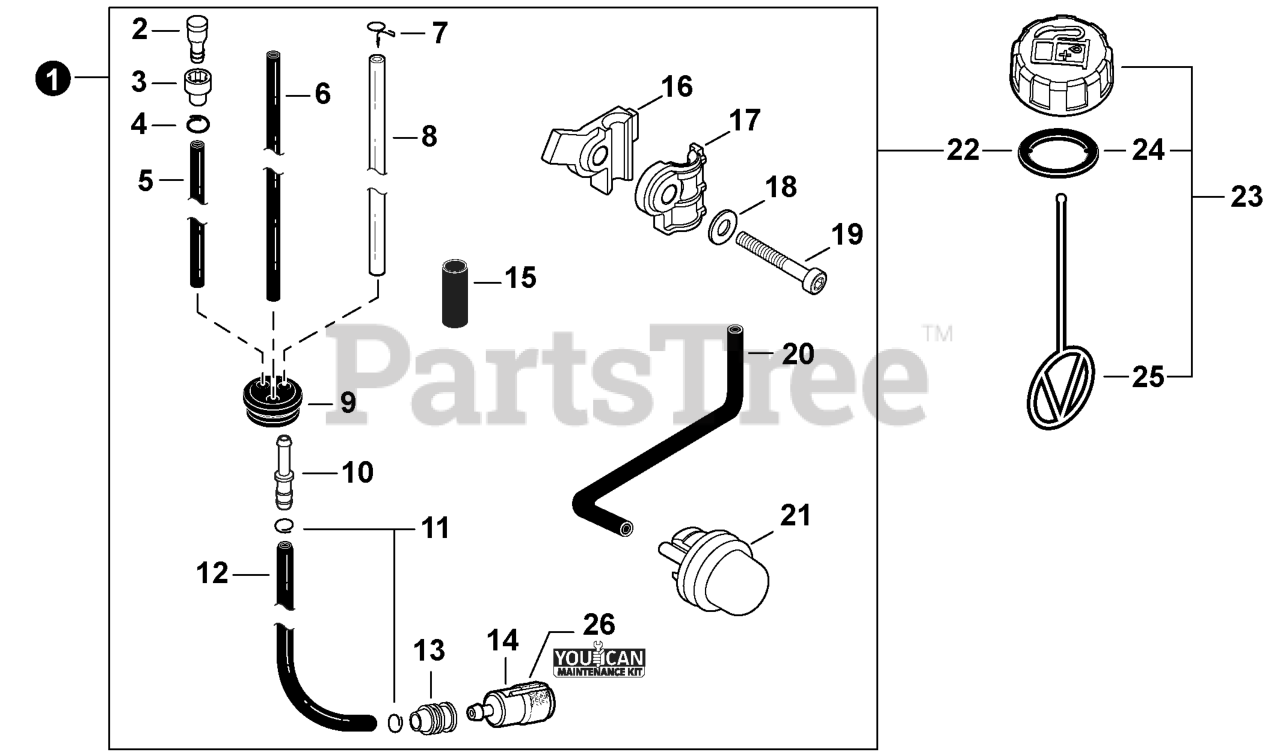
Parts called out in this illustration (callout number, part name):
1	FUEL SYSTEM KIT
2	VENT ASSY
3	HOLDER, VENT
4	CLIP 6.5 MM
5	PIPE, FUEL 3x6x130 BLACK
6	PIPE, FUEL 2.4x5x200 BLACK
7	CLIP, SPRING 5.2
8	PIPE, FUEL 3.5x6x210 CLEAR
9	GROMMET, FUEL
10	CONNECTOR, PIPE 5x3.5
12	PIPE, FUEL 3x5x105L BLACK
14	FILTER, FUEL
15	TUBE, FUEL LINE 16x18xL40
16	CLAMP, LOWER
17	CLAMP, UPPER
18	WASHER, FLAT 5.5x10x0.8
19	BOLT, TORX 5x25
20	PIPE, PURGE 2.4x5x140 BLACK
21	BULB, PURGE
22	GASKET, FUEL CAP
23	CAP ASSY, FUEL
24	GASKET, FUEL CAP
25	CONNECTOR, CAP L= 100 MM
26	TUNE-UP KIT - YOUCANT
